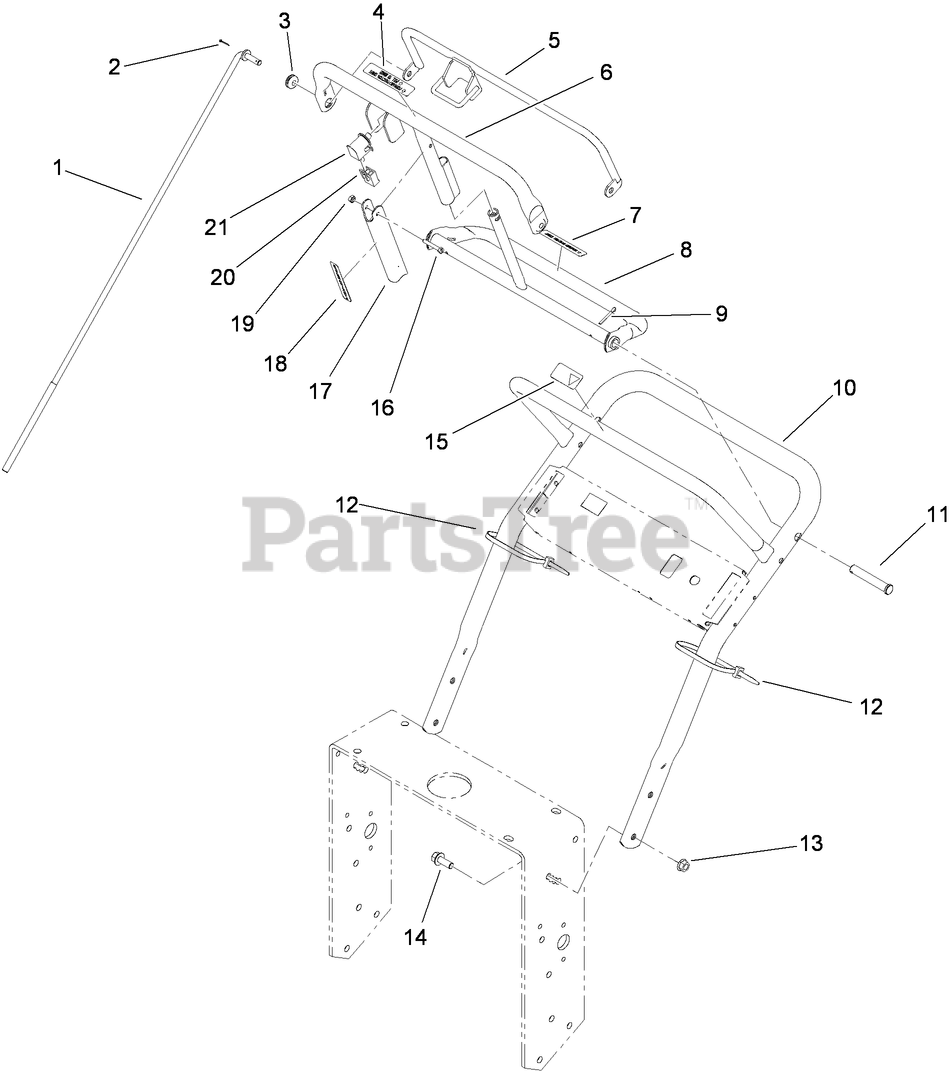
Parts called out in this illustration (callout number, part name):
1	ROD-CONTROL
2	PIN-COTTER
3	GROMMET-RUBBER
4	DECAL
6	BAR-CONTROL
7	DECAL
8	PIVOT-CONTROL
9	PIN-COTTER
10	HANDLE-UPPER
11	PIN-CLEVIS
12	TIE-CABLE
13	NUT-HF
14	SCREW-HHF
15	DECAL-PROTECTION, EAR
16	SCREW-SHH
17	LEVER-BRAKE, PARKING
18	DECAL-LEVER, PARKING
19	NUT-LOCK, NI
20	CONNECTOR-BODY
21	SWITCH-BAIL
